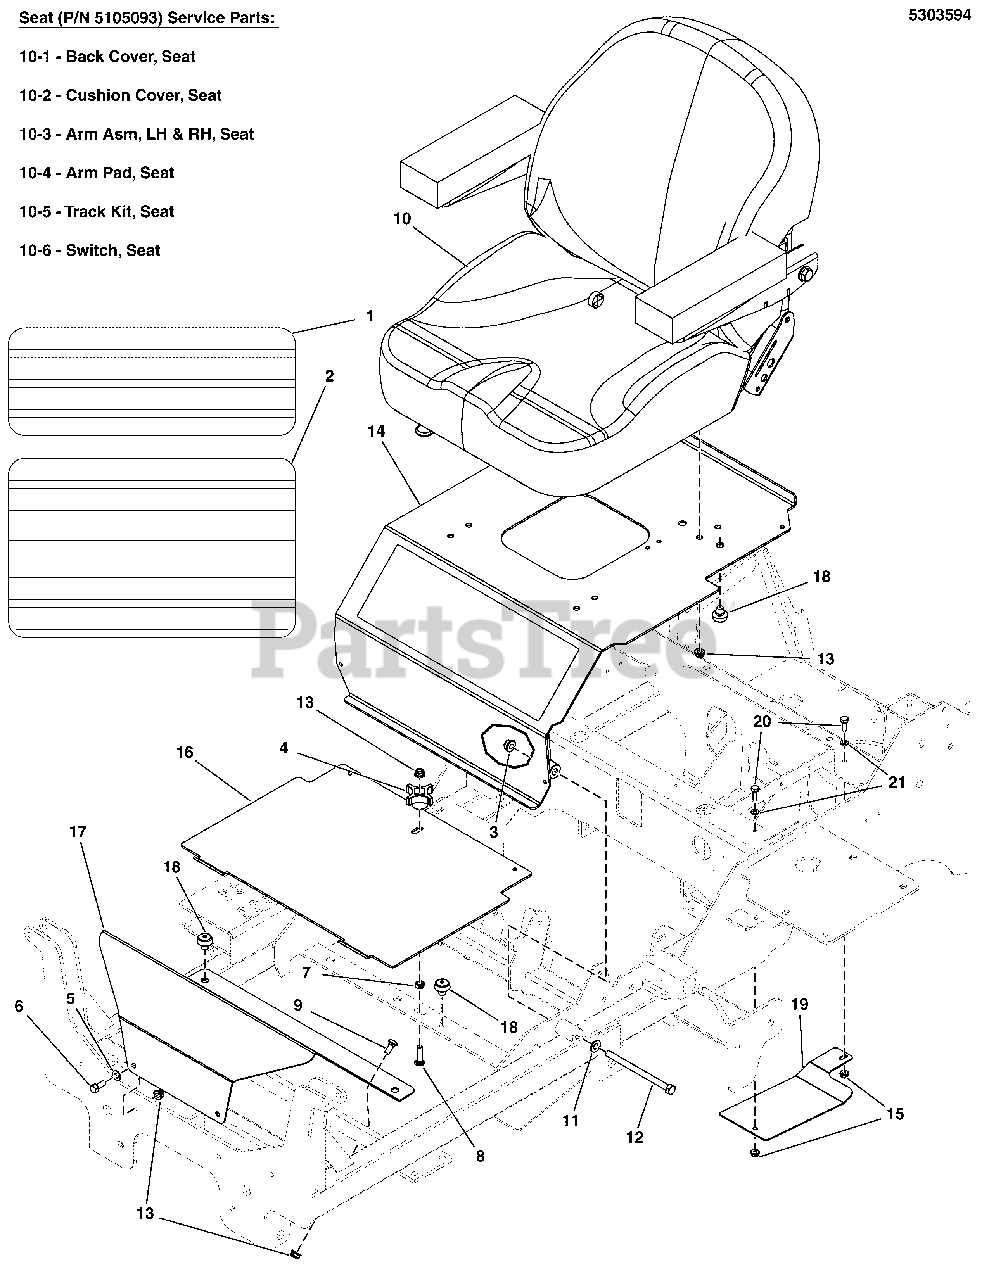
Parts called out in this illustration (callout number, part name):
1	SAFETY WALK, FLOOR REST, 6.00 X 16.00
2	SAFETY WALK, FLOOR PLATE, S50X, 10X16
3	NUT, 3/8-16 HEX NYLOCK FLANGE
4	KNOB-INT THR .312-18 4-ARM 2.12WD 1.06LG
5	WASHER, 5/16 SAE
6	BOLT, 5/16-18 X 3/4 GD5 CZ
7	NUT, 5/16-18, HEX, CNTR LK,ZINC PHOS/OIL
8	BOLT, 5/16-18 X 1-1/4, CARRIAGE, GD5, CZ
9	BOLT, 5/16-18 X 3/4, CARRIAGE, GD5, CZ
10	SEAT, C13, SEAT'SINC, 2016, W/SWITCH
10-1	BACK COVER, C13 SEAT
10-2	CUSHION COVER, C13 SEAT
10-3	ARM ASM, lh & RH, C13 SEAT
10-4	PAD
10-5	TRACK KIT, C13 SEAT
10-6	SWITCH, SEAT
11	WASHER, 3/8 SAE
12	BOLT, 3/8-16 X 5-1/2 GD5 CZ
13	NUT, 5/16-18 HEX NYLOCK FLANGE
14	ASSM, SEAT PLATE W/ DECALS, COBALT
15	NUT, 1/4-20 HEX SERR. FLANGE
16	PLATE, FLOOR, REMOVABLE, IS700 - ORG
17	PLATE, FRONT FLOOR, IS2000 - ORG
18	MNT, VBRTN, RBBR
19	GUARD, DEBRIS, IS2100Z - BLK
20	BOLT, 1/4-20 X 3/4 GD5 CZ
21	WASHER, 1/4 SAE
